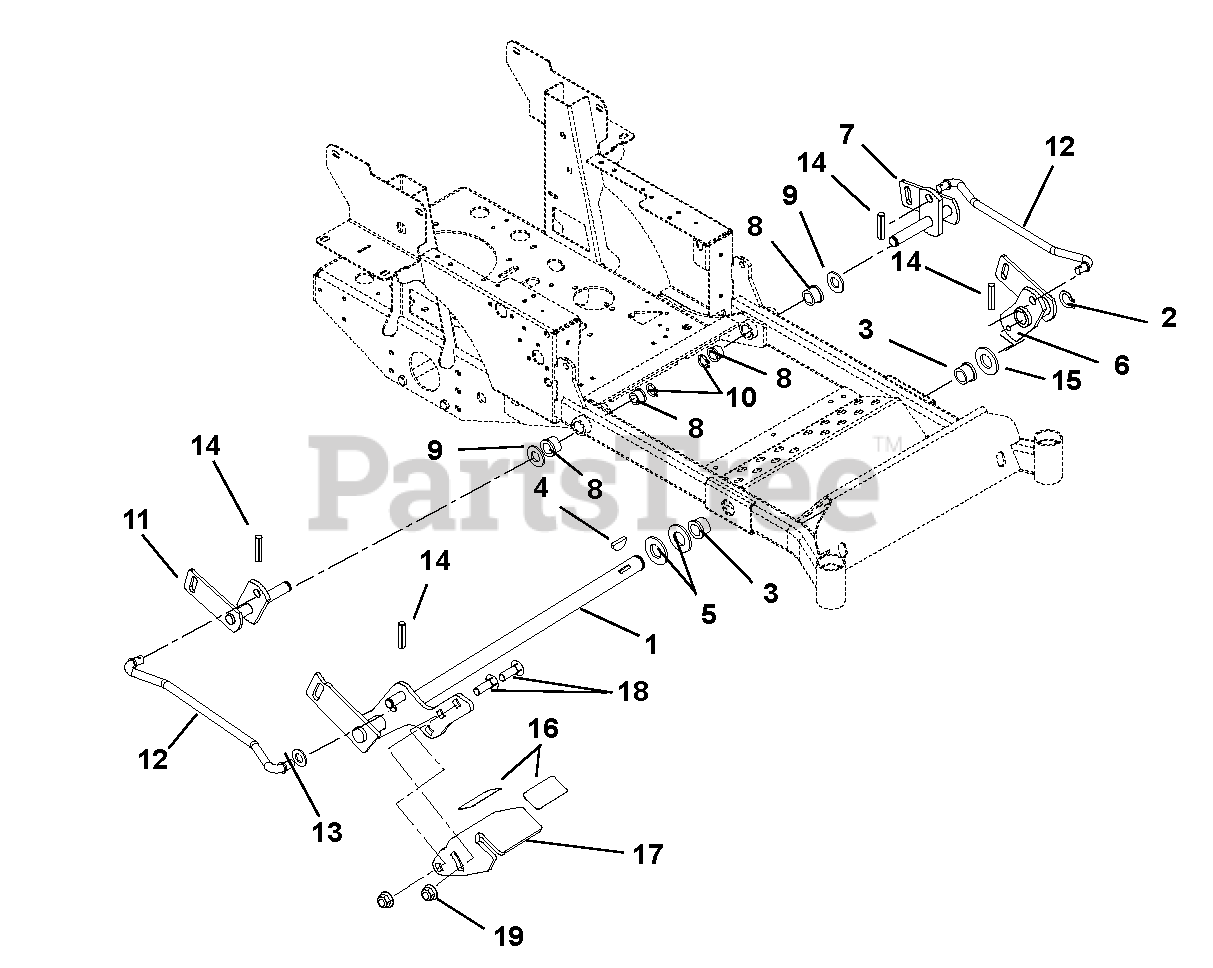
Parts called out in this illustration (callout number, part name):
1	Weldment, Mechanical Deck Lift
2	Ring, Retaining External 1.00 x .078
3	Bushing, Flange Nylon 1.020 x 1.385 x .75 x 1.75
4	Key, Woodruff .25 x 1.00
5	Washer, Flat Steel 1.062 x 2.0 x .134
6	Weldment, Left Hand Mower Lift Arm
7	Weldment, Left Hand Rear Mower Lift Arm
8	Bushing, Flange Nylon .762 x 1.0 x .580 x 1.48
9	Washer, Hardened Steel .758 x 1.23 x .031
10	Ring, Retaining External .689 x .077
11	Weldment, Right Hand Rear Mower Lift Arm
12	Rod, Lift Assist
13	Washer, Flat Steel .630 x 1.25 x .062
14	Pin, Roll .25 x 1.25 Stainless Steel
15	Washer, Hardened Thrust 1.00 x 1.55 x .03
16	Grip, Pedal
17	Foot Pedal, Adjustable Black
18	Bolt, Round Hd. Square Neck .50-13 x 1.50
19	Nut, Locking Top Flange .50-13
